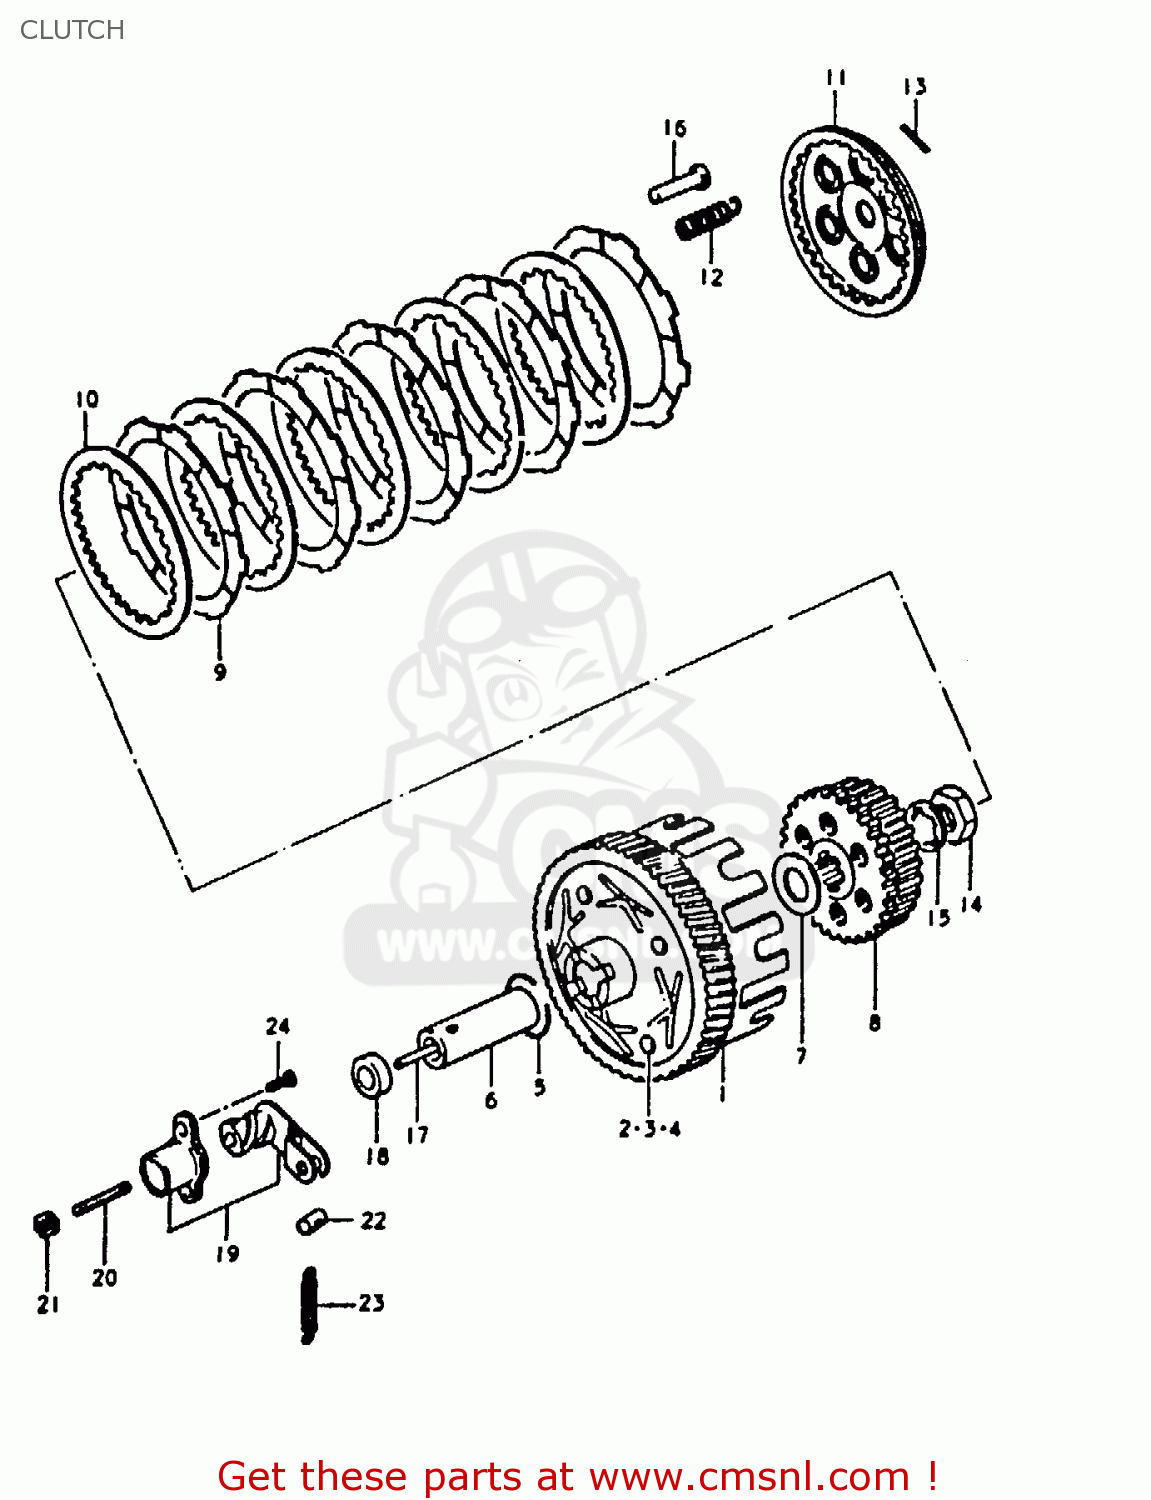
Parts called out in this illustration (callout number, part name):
7	WASHER
8	HUB,CLUTCH SLEEVE
9	PLATE,CLUTCH DRIVE (MCA)
10	PLATE,CLUTCH DRIVEN (NAS)
11	PLATE,CLUTCH PRESSURE
12	SPRING
13	PIN(2.5X19.8)
14	NUT
15	WASHER,LOCK
16	PIECE,CLUTCH PUSH
17	ROD,CLUTCH PUSH
18	SEAL,OIL(5.5X16X8)
19	SCREW ASSY,CLUTCH RELEASE
20	SCREW
21	NUT 6MM
22	PIECE,RELEASE ARM END
23	SPRING
24	SCREW 5X12
